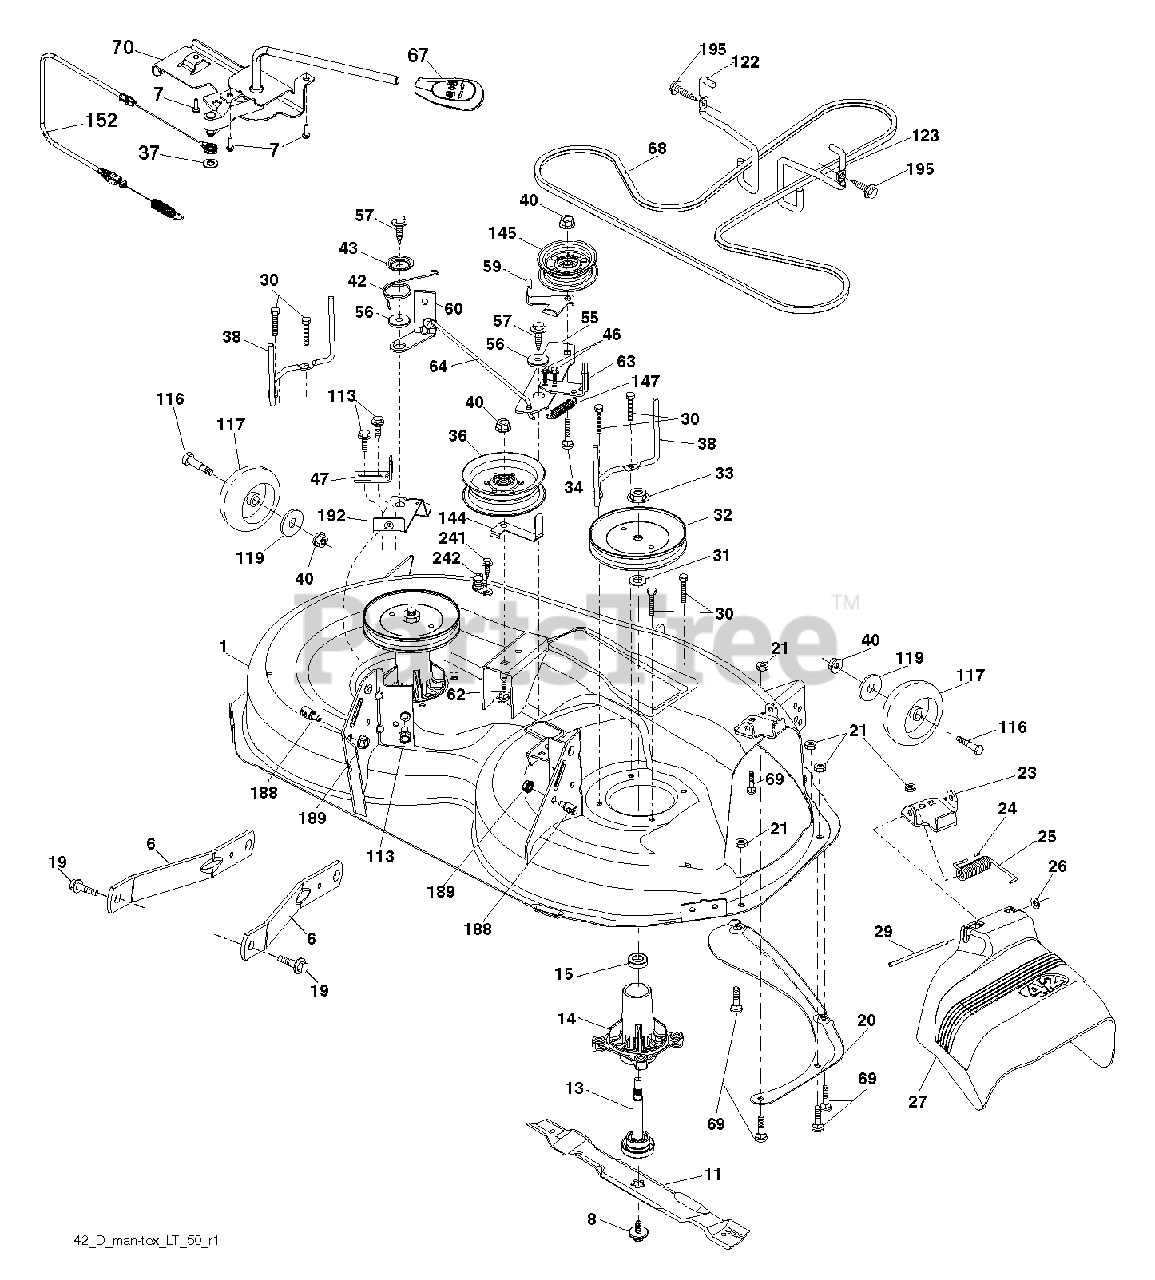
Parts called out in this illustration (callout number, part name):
6	ARM.SUSPENSION.MOWER.R
7	SCREW.#10 X 0.750.BOS (2 2)
8	BOLT.WASHER.ASM.7/16-2
11	42" HI-LIFT BLADE
13	SHAFT.ASM.MDRL.N/GREASE.38
14	HOUSING.MANDREL.4PT.
19	BOLT.SHOULDER
20	BAFFLE.VORTEX
21	LOCKNUT
23	BRKT.DEFLECTOR.38"2005+
24	CAP-SLEEVE LT
25	SPRING.TORSION.DEFLECT
26	NUT PUSH M
27	SHIELD.DEFLECTOR.MOWER.42"BLAC
29	ROD.HINGE
30	SCREW, WASHER HEAD
31	WASHER.SPACER.MANDREL
32	PULLEY.MANDREL.5.438.PD
33	NUT.FLANGE.LOCK.TOP
34	BOLT.3/8-16X1.50
36	PULLEY.IDLER.2006
38	KEEPER.BELT.MANDREL.PULLEY
40	NUT LOCK FLG 3/8-16 UNC
42	SPRING.TORSION.BRAKE
43	SRPING.TORSION.RETAINE
46	SCREW.1/4-20X5/8
47	BRKT.CLUTCH.CABLE
55	IDLER.ARM.42"
56	SPACER.RETAINER
57	SCREW 3/8-16X1
59	GUARD, BELT
60	ARM BRAKE MOWER
62	BOLT
64	LINK BRAKE
67	HANDLE.CLUTCH.CABLE.LT
68	BELT.DECK.DRIVE.42"
69	BOLT
70	CLUTCH.ASM.MANUAL.LT.TEX
113	BOLT.5/16HEX.WHS.HD
116	BOLT M
117	WHEEL.GAGE.HALF.SPOKED
119	WASHER
122	KEEPER BELT ENGINE LH
123	KEEPER BELT RH
144	KEEPER.BELT.MOWER
145	PULLEY.IDLER.48"PRIMARY
147	RETURN SPRING
152	CABLE.CLUTCH.MANUAL.
188	STUD.FASTNER.W/ANTI-ROTATE
189	NUT LOCK HEX FLANGE 5/16-18
192	BRKT.BRAKE.STAND.LH.
195	SCREW, 3/8-16X3/4
241	SCREW.TT.#10-32X.5.3/8.FLANGE
242	PORT.WASHOUT
